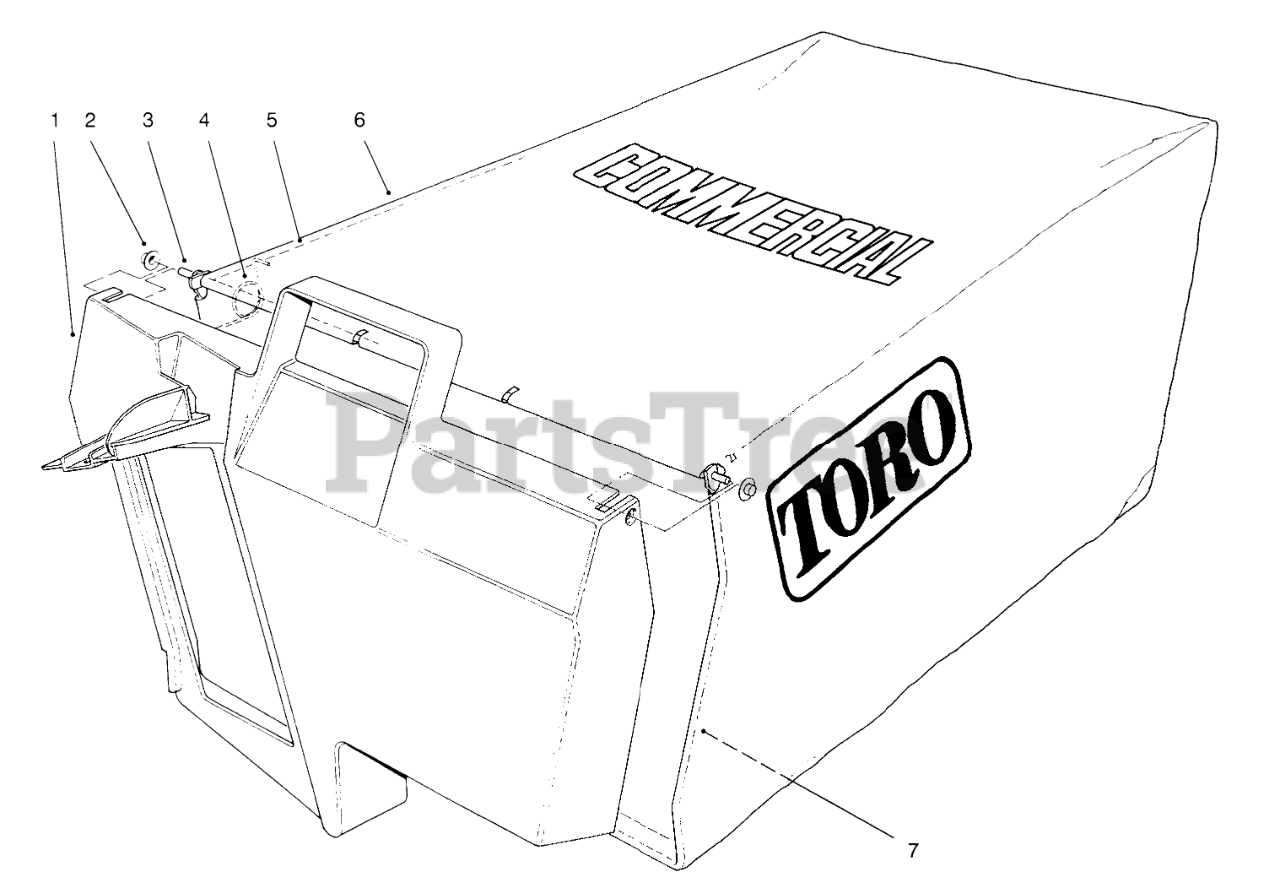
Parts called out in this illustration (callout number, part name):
1	DOOR-BAG, GRASS
2	NUT-PUSH
3	HINGE-DOOR, BAG
4	SPRING
5	FRAME-BAG, UPPER
6	Bag
7	FRAME-BAG
